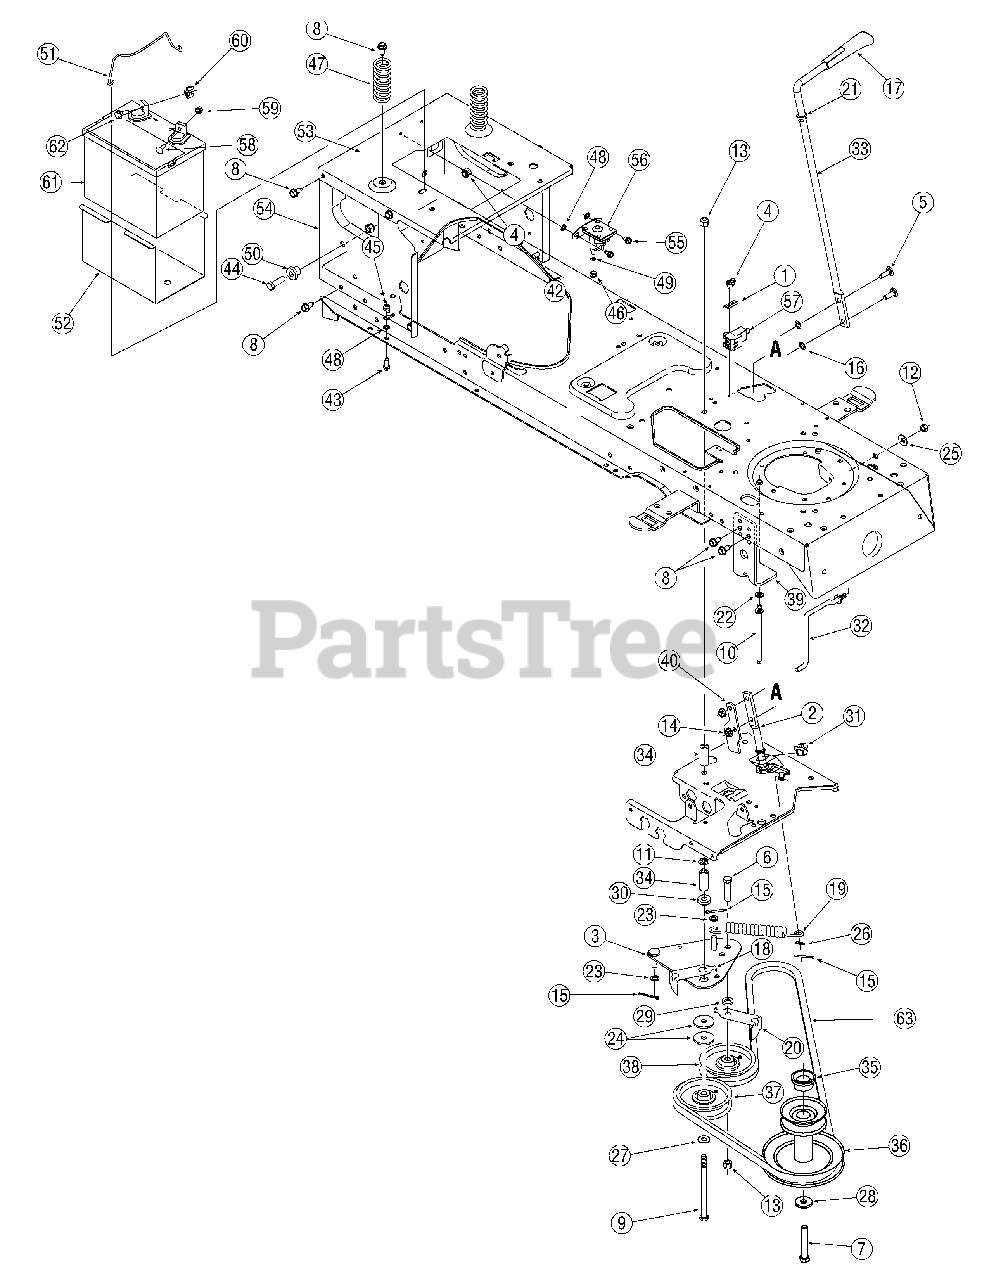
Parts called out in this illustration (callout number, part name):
1	Plate, Switch
2	Lever Assembly, Engagement
4	Screw, #10-16, 0.500
5	Screw, Carriage, 5/16-18, 1.00
6	Screw, 3/8-16, 1.75, Gr5
7	Screw, 7/16-20, 2.75, Gr5
8	Screw, 5/16-12, 0.750
9	Screw, 3/8-16, 5.50, Gr5
10	Pin, Belt Guard, 5/16 x 4.75
11	Nut, Push, 3/8
12	Nut, Flange Lock, 5/16-18, GrF, Nylon
13	Nut, Flange Lock, 3/8-16, GrF, Nylon
14	Nut, Flange Lock, 5/16-18, Gr5
15	Pin, Cotter, 1/8 x 1.25
16	Nut, Speed,.3125 ID
17	Knob, PTO
18	Belt Guard
19	Spring, Extension,.75 OD x 6.75
20	Belt Guard
21	Washer, Flat,.510 x.750 x.033
22	Washer, Lock, 5/16
23	Washer, Flat,.385 x.62 x.063
24	Washer, Flat,.390 x 1.500 x.134
25	Washer, Bell,.340 x.872 x.060
26	Washer, Flat,.344 x.688 x.065
27	Washer, Flat,.406 x.875 x.059
28	Washer, Flat,.450 x1.250 x.164
29	Washer, Flat,.407 x.812 x.135
30	Spacer, Shldr, 1.00 x.38 x.38
31	Bearing, Flange, Hex Split.500 ID
32	Keeper Rod, Belt
34	Spacer,.385 ID x.635 OD x 1.54
35	Spacer, 1.010 x 1.400 x.825
36	Pulley, Engine, 3.56 x 6.12 Diameter
37	Pulley, Idler, V-type 5/8 x 4.0 Diameter
38	Pulley, Idler, 3.50 Diameter
43	Screw, 1/4-20, 0.750
44	Screw, 3/8-16, 1.25, Gr5
45	Nut, Flange Lock, 1/4-20, GrF, Nylon
46	Nut, Hex, 1/4-20, Gr5
47	Spring, Compression, 1.28 OD x 3.125
48	Washer, Lock, 1/4, External
49	Washer, Lock, 1/4
50	Spacer, Shoulder,.38 x 1.0 x.70
51	Hold Rod, Battery
55	Screw, 1/4-20, 0.50
56	Solenoid, 12V, 100 Amp
57	Switch, Interlock
58	Screw, Carriage, 1/4-20,.75, Gr5
59	Nut, Sems, 1/4-20
60	Nut, Wing, 1/4-20
61	Battery, 190 CCA
62	Screw, Shoulder,.250 x.150, 1/4-20
63	V-Belt, PTO
